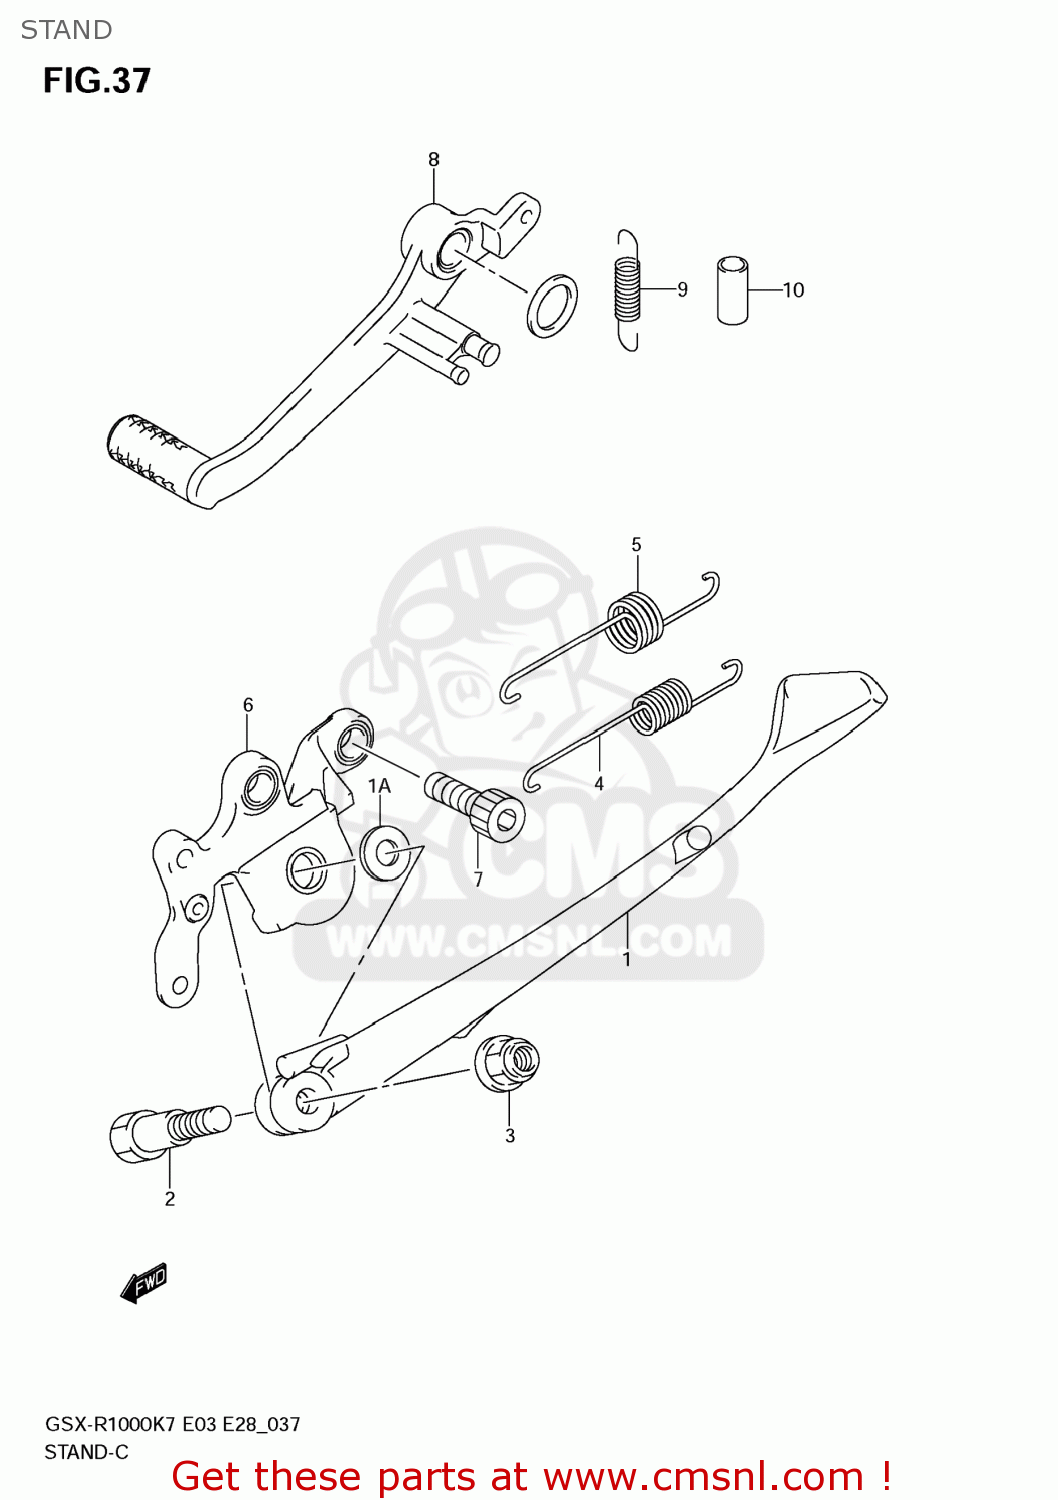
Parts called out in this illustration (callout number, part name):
1	STAND,PROP
1A	SEAT,VALVE SPRING EXH OUTER
2	BOLT(10X21)
3	NUT
4	SPRING
5	SPRING
6	BRACKET,PROP STAND
7	BOLT(12X26)
8	PEDAL,BRAKE
9	SPRING
10	HOSE(11X15X600)
